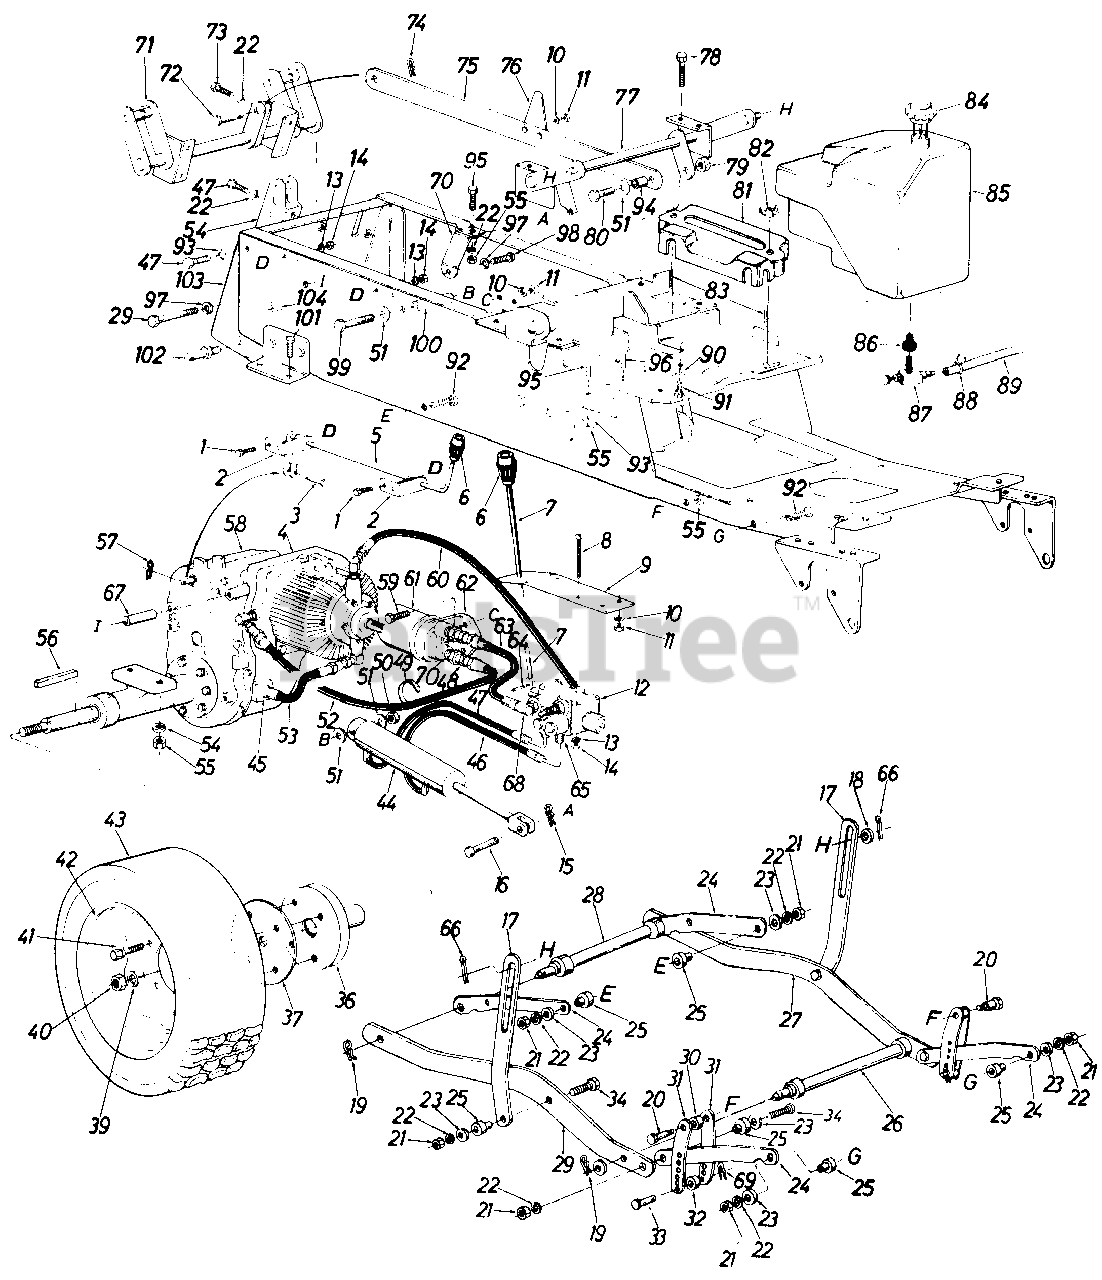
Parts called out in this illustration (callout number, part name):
1	Hex Bolt 1/4-20 x .75" Lg.
4	Hydrostatic Pump Comp.
5	Hi-Lo Control Handle Ass'y.
6	Shift Knob
7	Cylinder Control Handle Ass'y.
8	Truss Mach. Scr.1/4-20 x 3.00" Lg.
11	Hex Nut 5/16-18 Thd.
12	Valve Ass'y. Comp.
13	L-Wash. 1/4" I.D.
14	Hex Nut 1/4-20 Thd.
15	Hairpin Cotter 1/2" Dia.
16	Clevis Pin 1/2" Dia.
19	Hairpin Cotter
20	Shld. Bolt .498" Dia. x .66"
21	Hex Nut 3/8-24 Thd.
22	L-Wash. 3/8" I.D.- H.D.
23	Fl-Wash. .38" I.D. x 1.00"
26	Cross Shaft Ass'y.- Front
29	Hex Bolt 1/2-13 x 2.75"
30	Collar .50" I.D. x 1.0"
33	Clevis Pin 3/8" Dia.
34	Hex Bolt 3/8-24 x 1.50" Lg.- Grade 5
39	L-Wash. 3/4" I.D.
40	Hex Ins. L-Nut 3/4-16 Thd.
41	Wheel Lug Bolt
44	Hydraulic Cylinder
45	7/8-14 UNF-24 Thd. 5/8 Tube Fitting
46	Valve to Cylinder Hose - 20"
47	Hex Bolt 3/8-16 x .75" Lg.-Grade 5
48	Bushing Reducer 1/2-14 NPTF to 3/8-18 NPTF
49	Cable Tie
50	Hex Jam Nut 1/2-20 Thd.
51	Fl-Wash. .50" I.D. x 1.25
52	Filter Return Hose 24" Lg.
53	Pump Tube Ass'y.
55	Hex Nut 3/8-16 Thd.
56	Sq. Key 1/4" x 1/4" x 2"
57	Hairpin Cotter 1/4" Dia.
58	Peerless Transaxle (See Breakdown)
59	Hex Bolt 5/16-18 x 1.25"
60	Pump to Valve Hose
61	Fram Filter Ass'y. PH-16
62	Filter Base
63	Valve to Filter Hose - 8.38"
64	Spring Pin Spiral 1/8" Dia.
65	Flare Adapter
66	Cotter Pin 1/8" Dia. x 1.0"
67	Spacer
68	Adapter 9/16-18 to 9/16-18
69	Hairpin Cotter
70	Transmission Brace
73	Hex Scr. 3/8-16 x 1.00" Lg. Grade 5
74	Cotter Pin 1/8" Dia. x 1.25"
79	Hex Cent. L-Nut 1/2-20 Thd.
80	Hex Scr. 1/2-20 x 1.25" Lg.
81	Battery Cover
82	Wing Nut 1/4-20 Thd.
83	Battery Hold Down Rods
84	Gas Tank Cap
85	Gas Tank Ass'y.
86	Bushing
87	Fuel Shut-Off Valve with Screen
88	Gas Line Clamp 1/2"
89	Gas Line 26" Lg.
90	Bell-Wash.
91	Hex Scr. 1/4-20 x .38" Lg."
92	Hex Scr. 3/8-24 x 1.50" Lg.
93	L-Wash. 3/8" Scr.
94	Push Bar Sleeve
95	Hex Scr. 3/8-16 x 1.00" Lg.- Grade 5
96	Hex Scr. 5/16-18 x .75" Lg.
97	L-Wash. 1/2" Scr.
98	Hex Scr. 1/2-13 x 1.25" Lg.
99	Hex Scr. 1/2-20 x 31/2" Lg.- Grade 5
100	Spacer for Cylinder
101	Hex Scr. 3/8-16 x 1.75" Lg.
102	Link Clevis Pin
